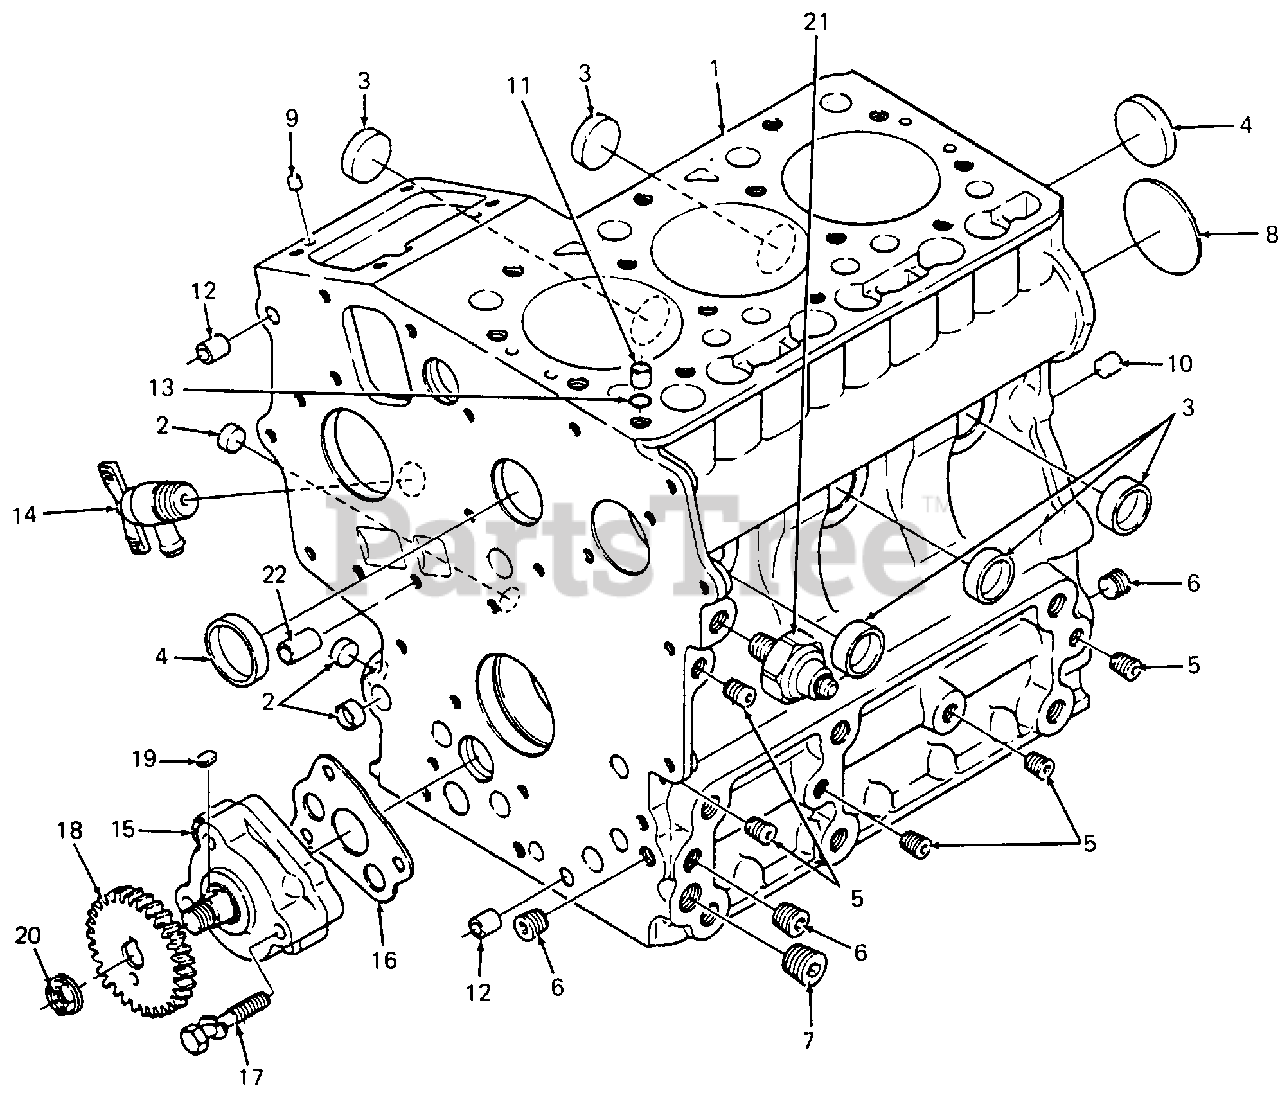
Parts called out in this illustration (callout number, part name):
1	Crankcase Assy
9	Pin, Straight
10	Pin, Straight
14	Handle, Drain Cock
16	Gasket, Oil Pump
17	Screw, Hex Cap w/Washer
18	Gear, Oil Pump Drive
21	Switch, Oil
